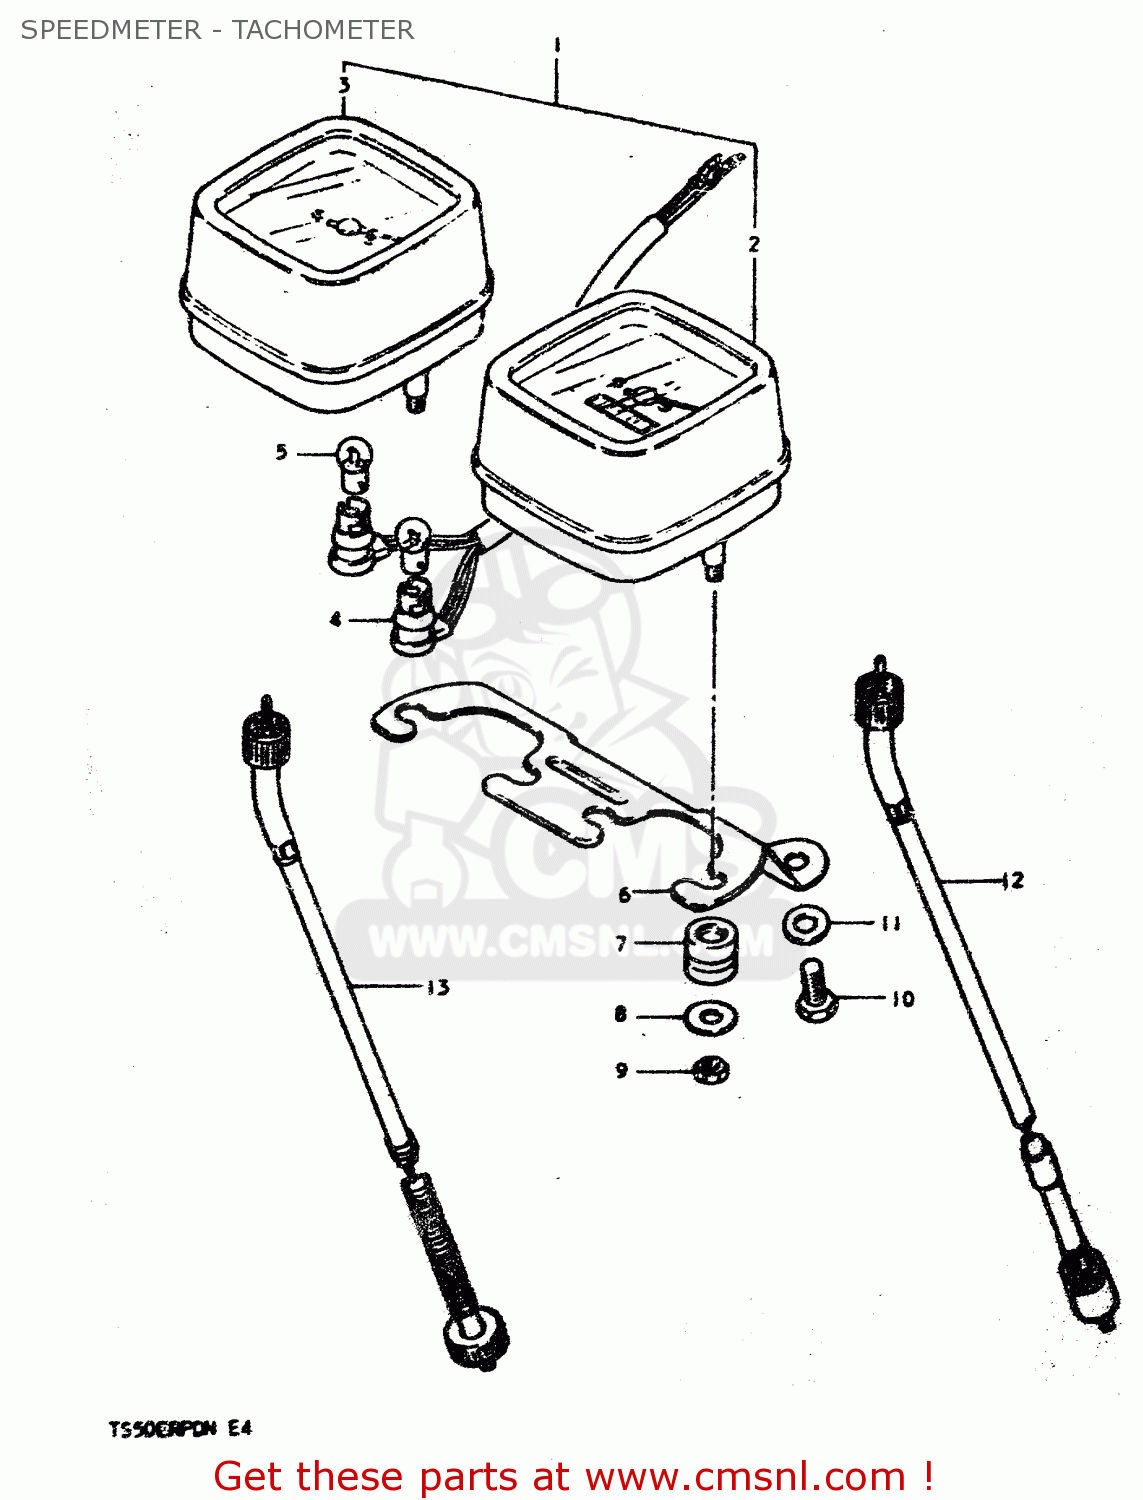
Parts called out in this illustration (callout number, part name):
1	SPEEDOMETER & TACHOMETER ASSY
2	SPEEDOMETER
3	TACHOMETER
4	SOCKET,METER
5	BULB(6V1.7W,STANLEY,A61A)
6	BRACKET,METER
7	CUSHION
8	WASHER,METER
9	NUT
10	BOLT, UPPER
11	WASHER
12	CABLE ASSY, SPEEDOMETER
13	CABLE ASSY, TACHOMETER
